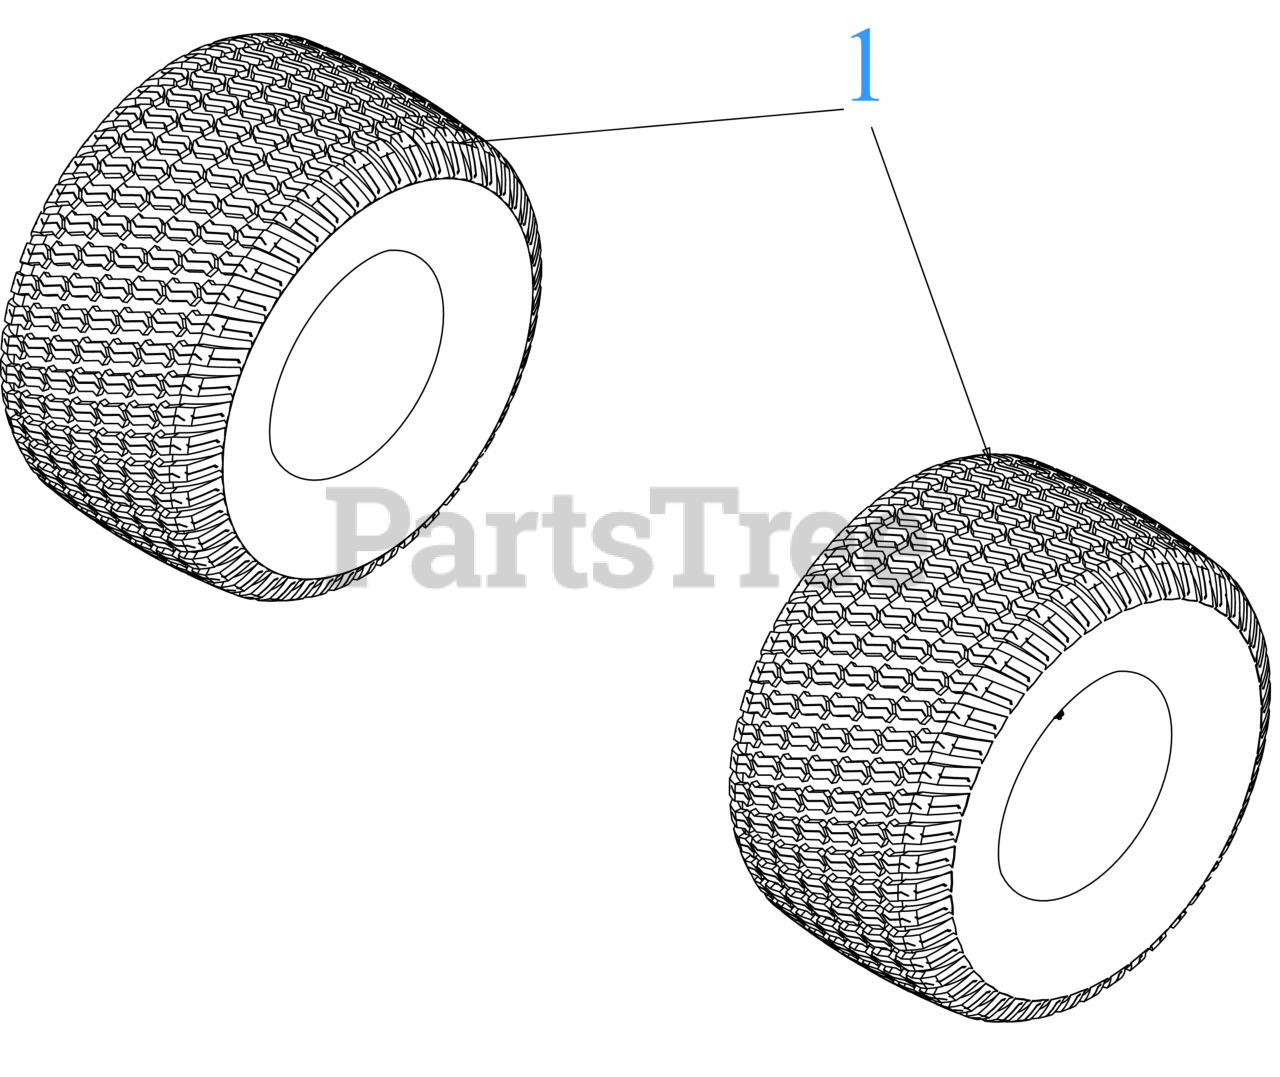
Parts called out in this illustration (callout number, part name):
1	COMPLETE WHEEL (20X12-8 2 PLY TMSTR)
1	RIM ASSEMBLY (8X8.5)
1	TIRE (20X12-8 2PLY TURFMASTR)
1	TUBELESS AIR VALVE
